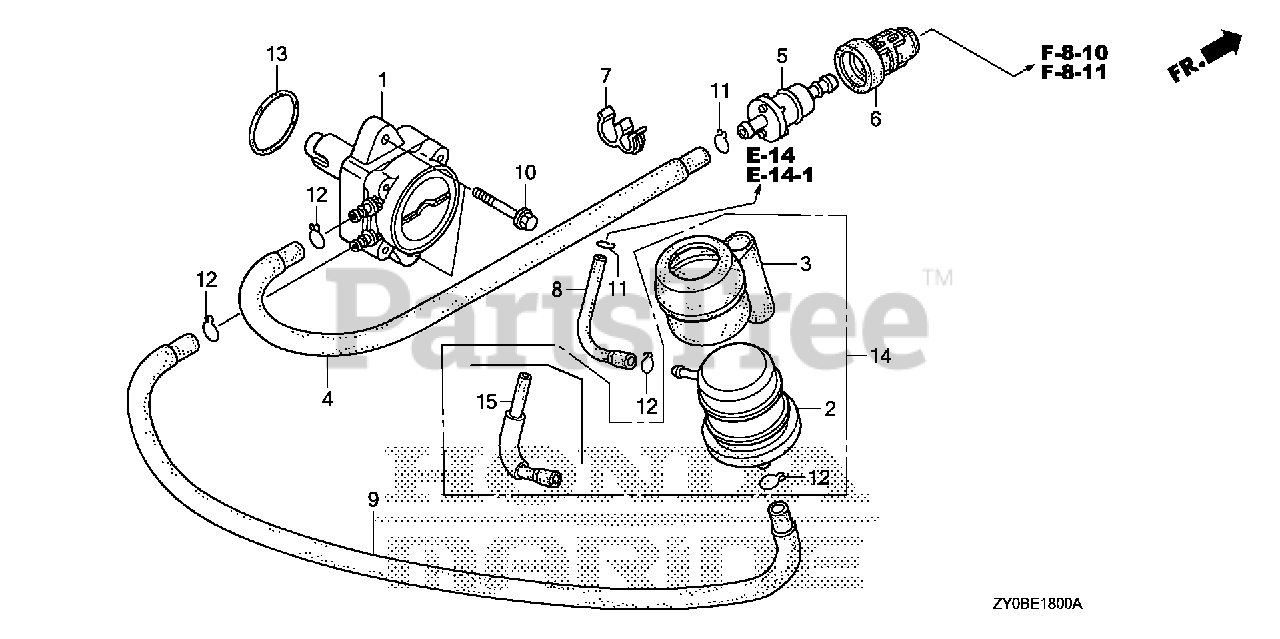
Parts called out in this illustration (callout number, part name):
1	PUMP ASSY., FUEL (MSDS)
2	CHAMBER, FUEL
3	SUSPENSION, FUEL CHAMBER
4	TUBE B, FUEL
5	FILTER, FUEL
6	SUSPENSION, STRAINER
7	CLAMP, TUBE (7.5-11.5) (BLACK)
8	TUBE D, FUEL
9	TUBE C, FUEL
10	BOLT, FLANGE (6X22)
11	CLIP, TUBE (B10)
12	CLIP, TUBE
12	CLIP, TUBE (B12)
13	O-RING (31.2X2.4)
14	CHAMBER KIT, FUEL
15	TUBE D, FUEL
